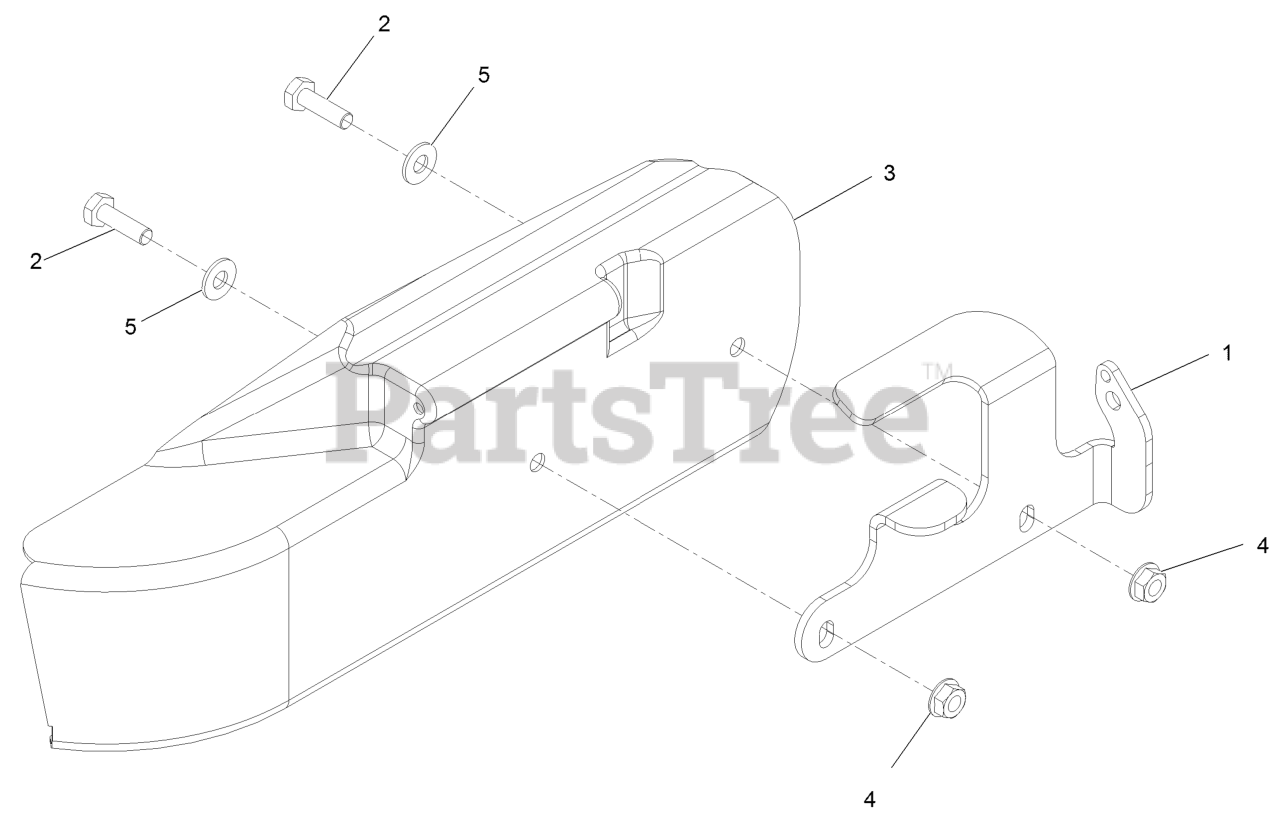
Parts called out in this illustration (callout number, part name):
1	BRACKET-DEFLECTOR, SIDE
2	SCREW-HH
3	DEFLECTOR-SIDE
5	WASHER-FLAT
